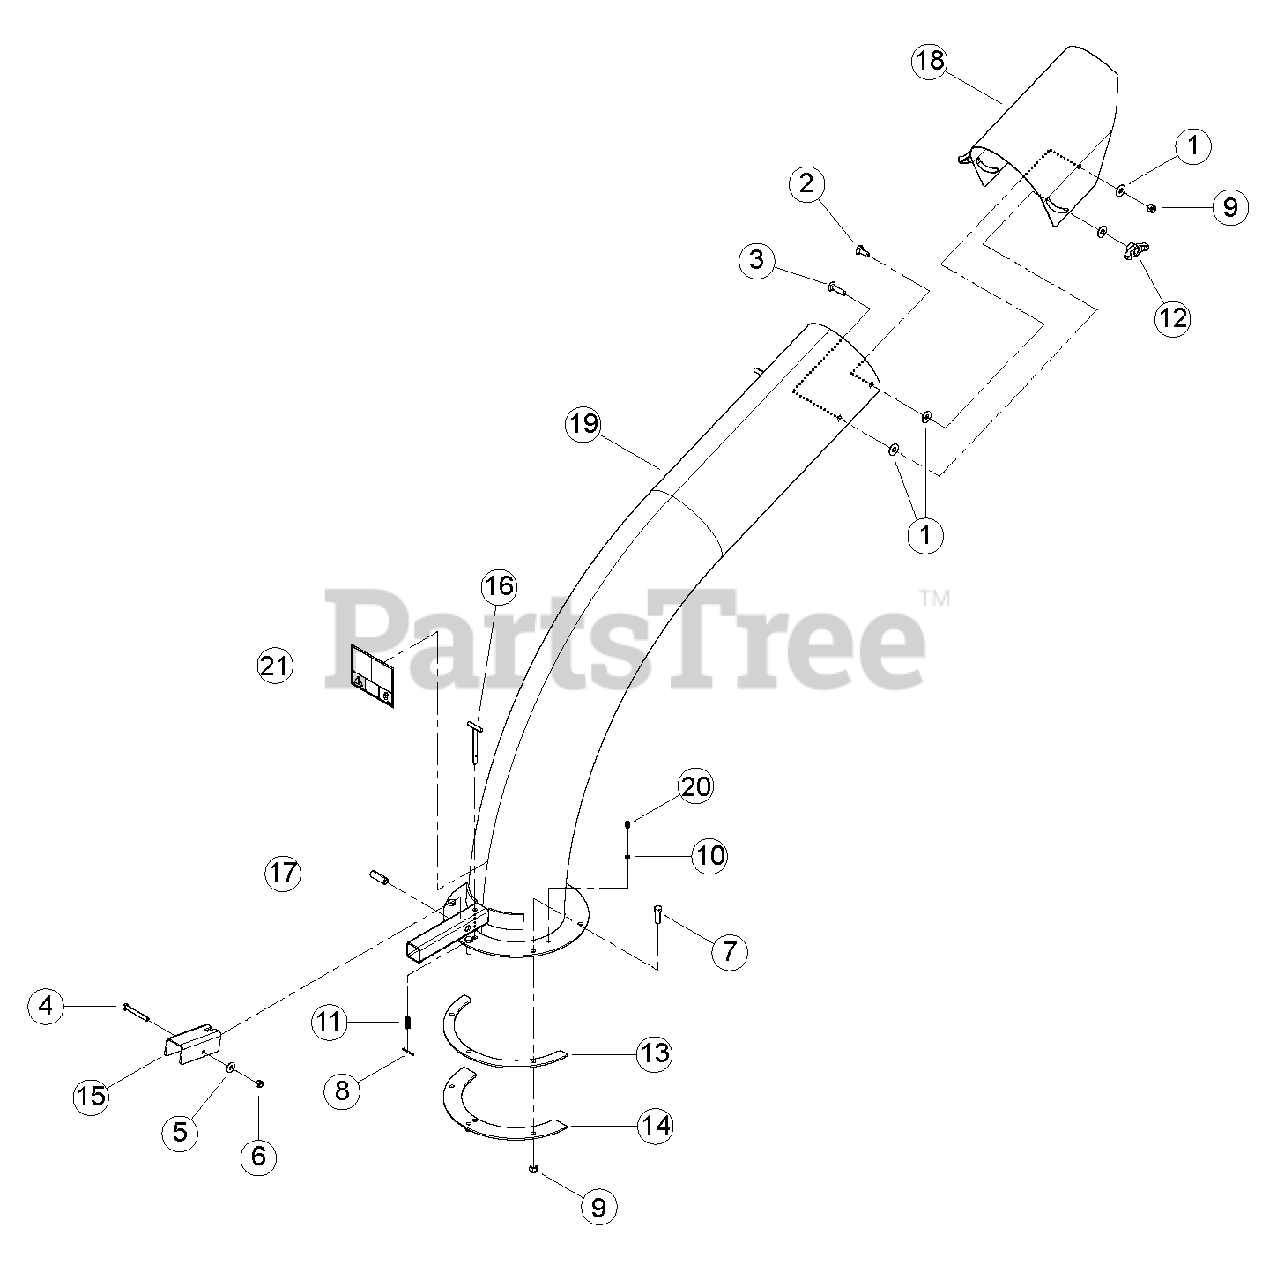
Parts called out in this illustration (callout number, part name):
1	WASHER, 3/8 FLAT ZP
2	BOLT, 3/8 X 1 CRG GR5 NC ZP
3	BOLT, 3/8 X 1-1/2 CRG GR5 NC ZP
4	BOLT, 5/16 X 2-1/2 HX CAP GR5 ZP
5	WASHER, 5/16 FLAT ZP
6	NUT, 5/16 NE NYLOCK ZP
7	BOLT, 3/8 X 1-1/4 HEX HD GR5 ZP
8	PIN, 1/8 X 1 ZP COTTER
9	NUT, 3/8 NE NYLOCK ZP
10	WASHER, .254 X .400 X .048 FLAT
11	SPRING, LOCK COMPRESSION
12	KNOB, 3/8-16 UNC FEMALE TEE
13	RING, DISCHARGE SPACER
14	RING, DISCHARGE CLAMP
15	LEVER, DISCHARGE LOCK
16	WELDMENT, DISCHARGE LOCK PIN
17	TUBE, DISCHARGE LOCK PIVOT
18	CAP, 8 IN. DISCHARGE CHUTE
19	ASSEMBLY, 8 INCH DISCHARGE SERVICE PART
20	FITTING, 1/4 SELF-TAP GREASE
21	DECAL, DISCHARGE DEBRIS & LOCK
